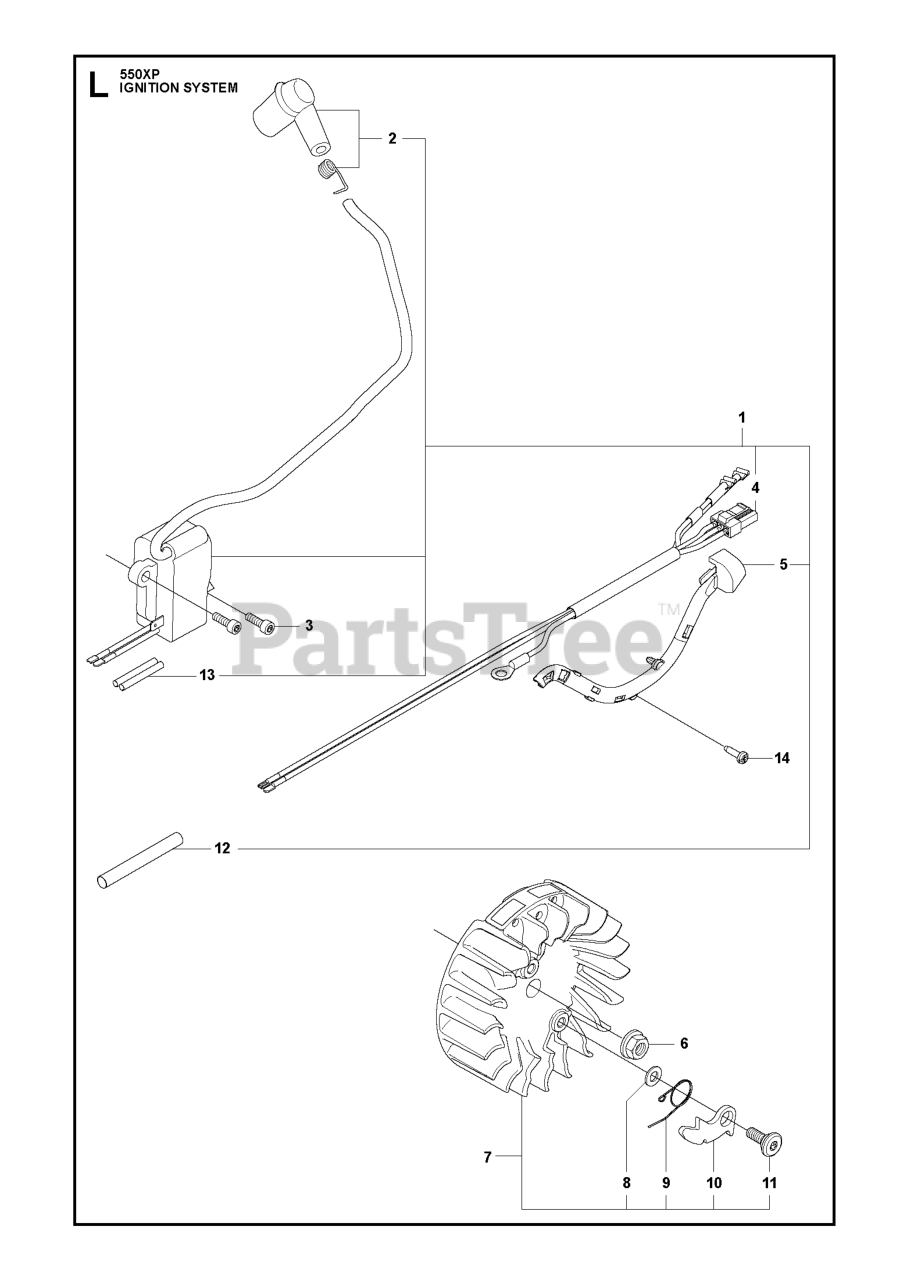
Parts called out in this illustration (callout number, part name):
1	IGNITION MODULE ASSY
2	SPARK PLUG CAP ASSY
3	SCREW ITXSCFM
4	WIRING ASSY IGNITION SYSTEM
5	CABLE HOLDER
6	NUT W/ WASHER
7	FLYWHEEL ASSY
11	SCREW
12	CABLE COVER
13	SHRINK HOSE
14	SCREW CITXPANT
